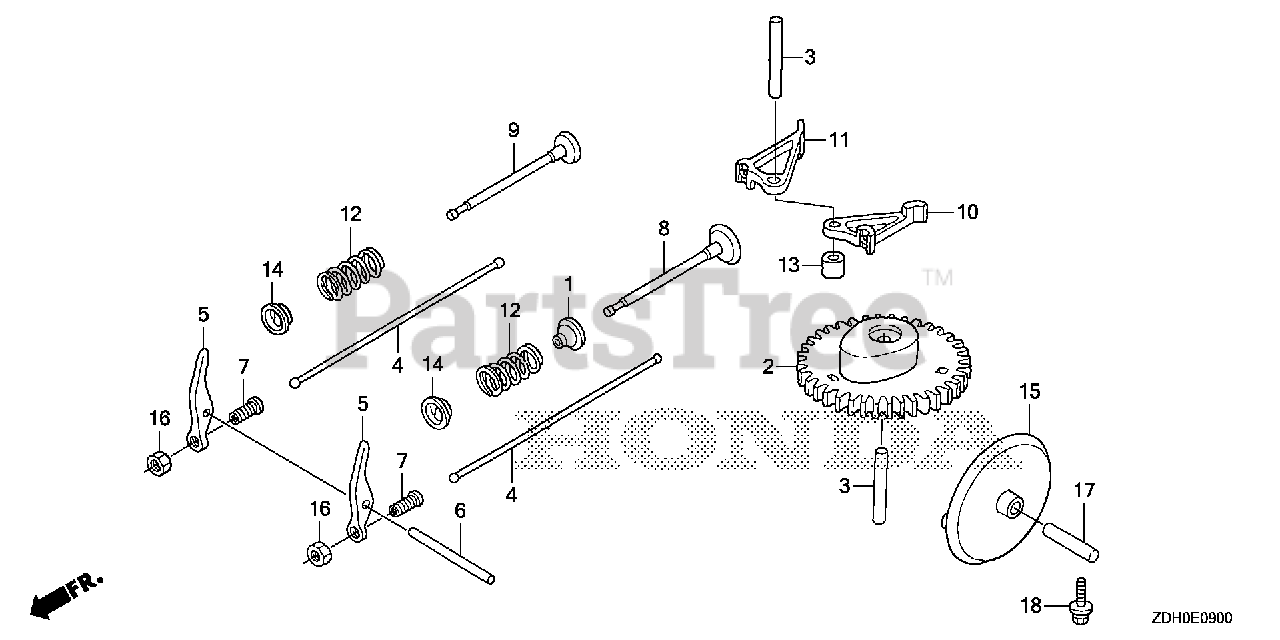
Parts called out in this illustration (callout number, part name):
1	SEAL, VALVE STEM
2	CAMSHAFT ASSY.
3	ROLLER (5X29.8)
5	ARM, VALVE ROCKER
6	ROLLER (4X37.8)
7	PIVOT, ROCKER ARM
8	VALVE, IN.
9	VALVE, EX.
10	LIFTER, VALVE
11	LIFTER, EX. VALVE
12	SPRING, VALVE
13	COLLAR, LIFTER
14	RETAINER, VALVE SPRING
15	SLINGER, OIL
16	NUT, TAPPET ADJUSTING
17	ROLLER (6X25)
18	BOLT-WASHER (5X16)
